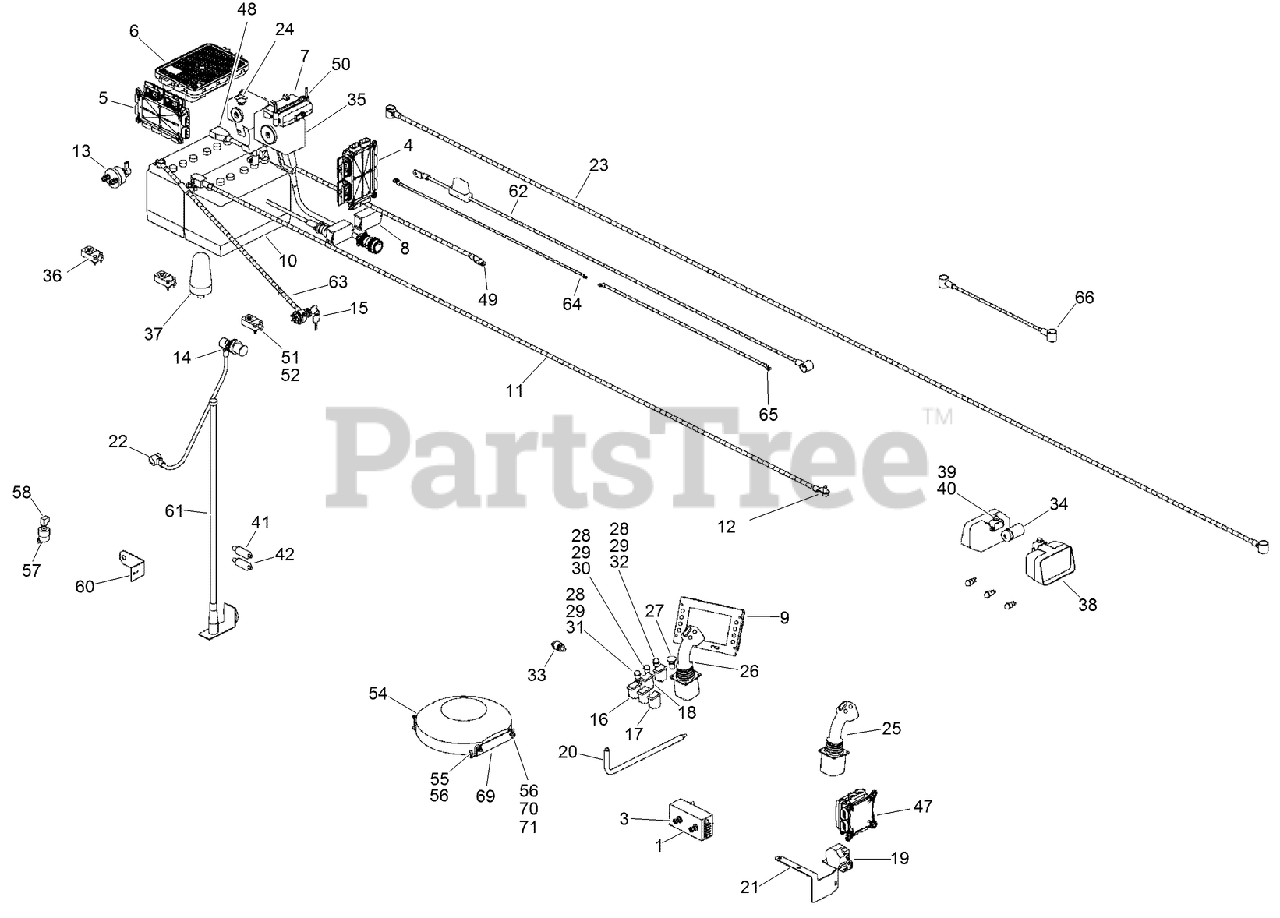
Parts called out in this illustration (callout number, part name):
3	NUT-HEX
4	BOX-VEC, MAIN (A)
5	BOX-VEC, MAIN (B)
6	CONTROLLER - Programmed, MC88
7	COMPUTER-EXPANDER, OUTPUT
8	CONNECTOR-PACK, RESISTOR
9	DISPLAY - Programmed
10	DISPLAY-DP600, UNPROGRAMMED
11	PROGRAM - DD4045
12	BATTERY
12	SCREW, METRIC FLANGE FULL - M12 x 20
13	SWITCH-DISCONNECT, MASTER
14	POST-BATTERY, REMOTE
15	ASSEMBLY - Ignition Switch
16	SWITCH-ROCKER, 2 POLE (ON/OFF)
17	SWITCH-ROCKER, 2 POLE
18	SWITCH-ROCKER, 1 POLE (ON)OFF/ON(OFF)
19	ALARM-BACKUP
20	ASSEMBLY - Ground Stake
21	PLATE - Mount
22	CABLE - Starter
23	CABLE - Power to Starter
24	TRAVEL PENDANT
25	JOYSTICK-CARRIAGE
26	JOYSTICK-MODIFIED (LEFT HAND)
27	BUTTON-PUSH, RED MUSHROOM
28	TYPE T-2 SOCKET ASM
29	BULB-TYPE T-2, 12VOLT
30	LENS-DOME, FLUTED GREEN (TYPE T2)
31	LENS-DOME, FLUTED RED (TYPE T-2)
32	LENS-DOME, FLUTED AMBER (TYPE T2)
33	SWITCH - Pushbutton
34	POWER OUTLET - Electical
35	LIFEJACKET
36	SWITCH-PROXIMITY
37	ASSEMBLY - Strobe, Small
38	LIGHT - Flood
39	SCREW-HH
40	WASHER-0.406 x 0.812 x 0.065 in CST ZND
41	TRANSDUCER - 5300 PSI, 7/16 - 20 SAE
42	TRANSDUCER - 3300 PSI, 7/16 - 20 SAE
47	BOX-VEC, MAIN (C)
48	CABLE - Dual Battery, Red (Positive)
49	CABLE - Battery (Positive)
50	SCREW, METRIC FLANGE w/BODY - M6 x 80
51	SCREW - PHD Type 1, #10 - 24 x 1.00 CST ZND
52	NUT-#10-24 KEPS
54	FAN - Electric
55	SCREW, METRIC FLANGE w/BODY-M6 x 25
56	NUT, METRIC FLANGE PREVAILING - M6 Zinc
57	SWITCH ASM
58	FITTING-ELBOW, 90
60	PLATE - Bracket
61	ANTENNA - Long Range
62	CABLE - Fused Starter to Start Heater
63	CABLE - Ground Strap.
64	CABLE - 4 AWG Weld, Alt to Starter
65	CABLE - 4 AWG Weld, Red, Alt to Starter
66	CABLE - Elec, Solenoid to Grid Heater
69	Plate, Fan Mount
70	BOLT - Thd to Hd, M6 x 20 CL8.8 Pln
71	WASHER-FLAT
